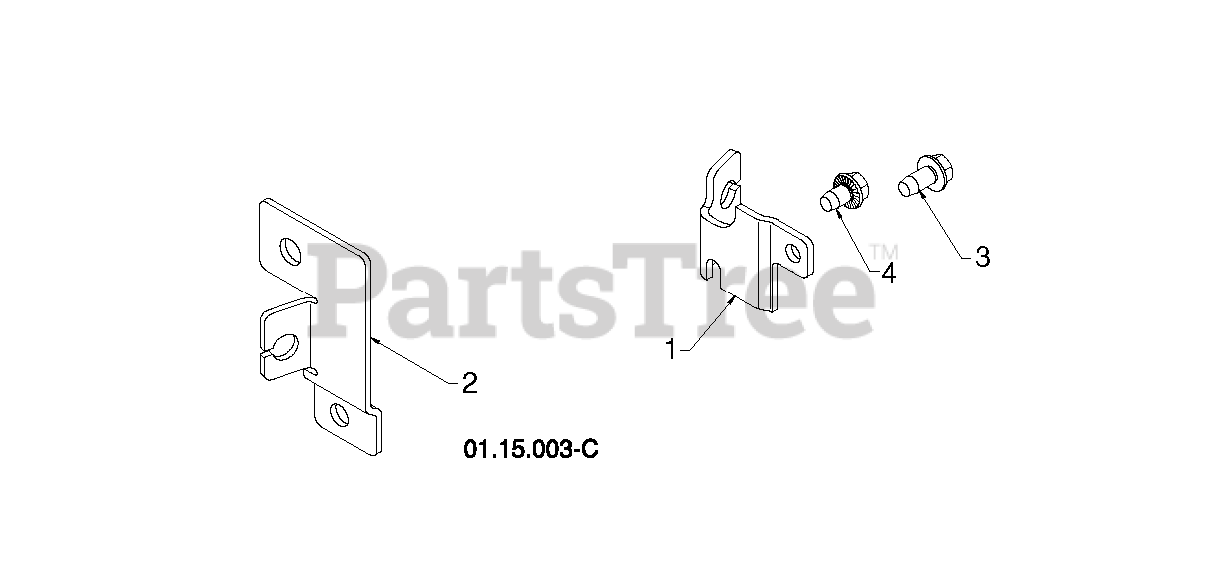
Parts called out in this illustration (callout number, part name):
1	BRACKET.STEER.CABLE.LH
2	BRACKET.STEER.CABLE.RH
3	SCREW
4	SCREW 1/4X20
